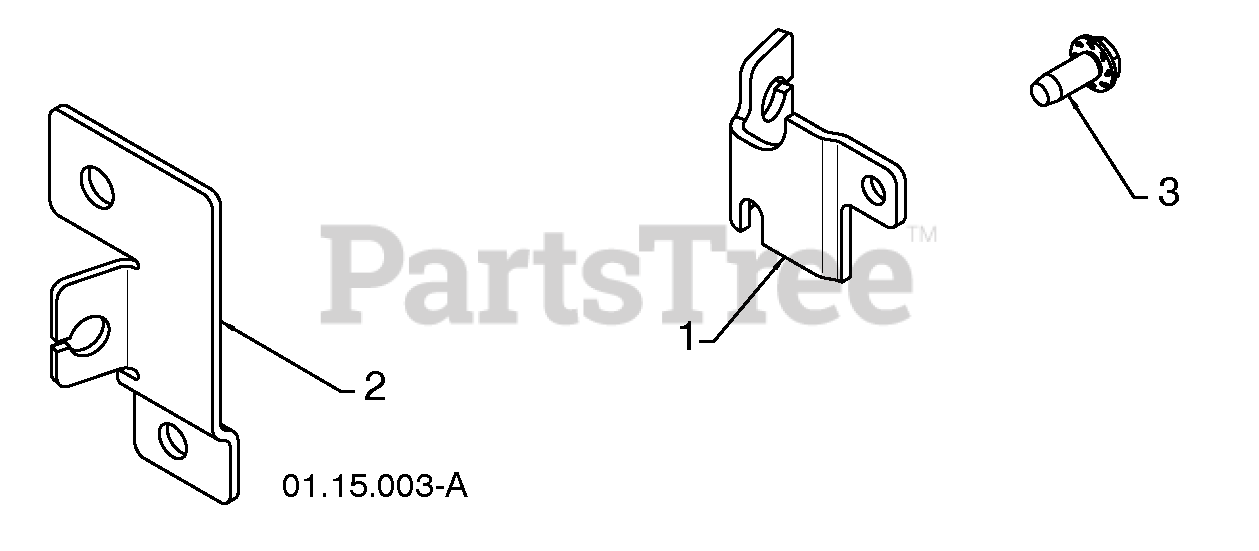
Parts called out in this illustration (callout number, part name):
1	CABLE BRACKET LH
2	CABLE BRACKET RH
3	SCREW 1/4-20 X .625
